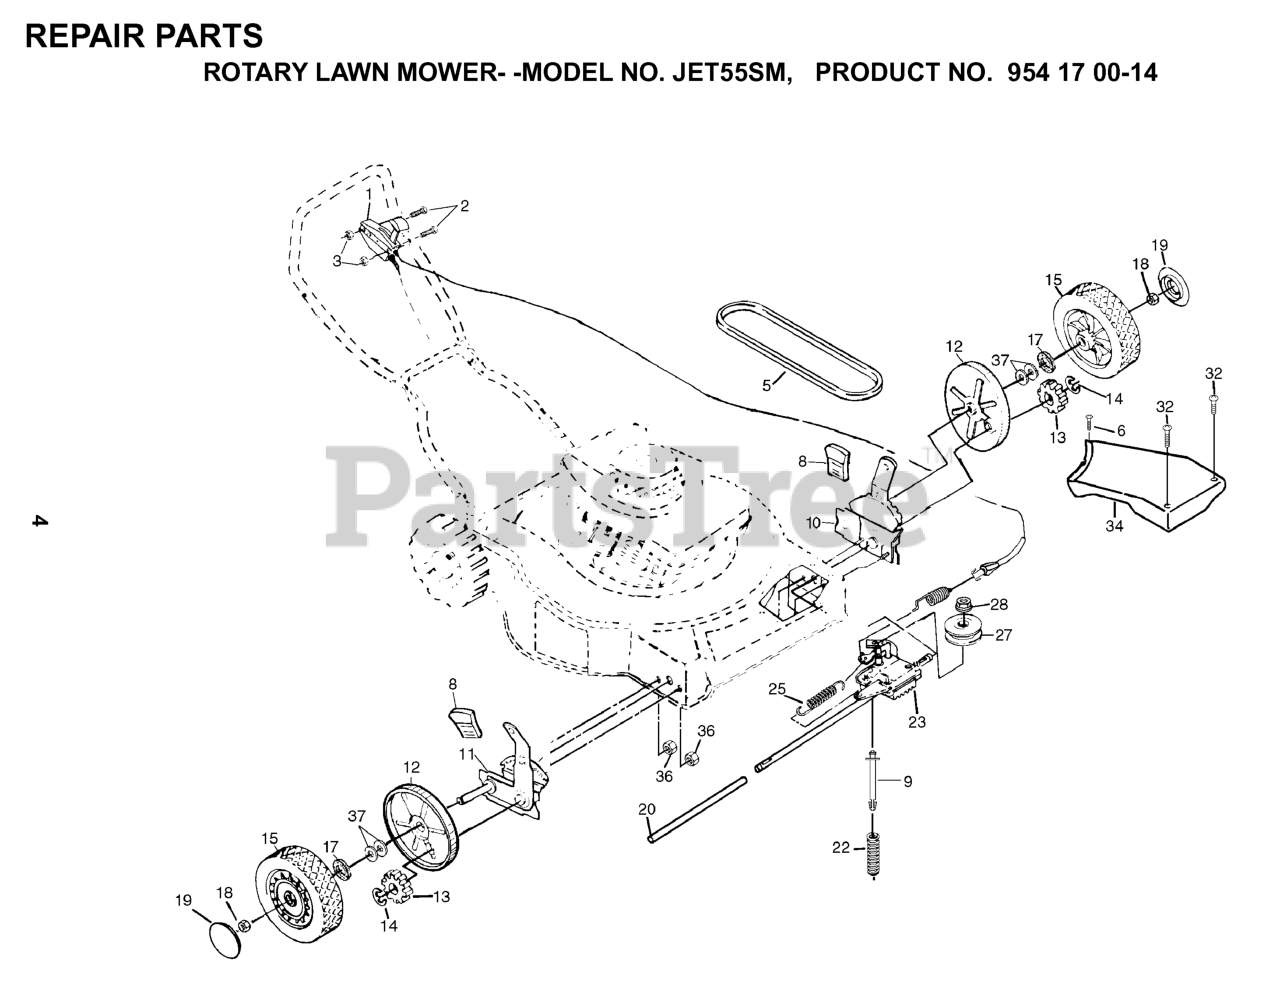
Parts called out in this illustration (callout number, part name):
1	DRIVE CONTROL
2	SCREW 1/4-20 X 2.12
3	NUT
5	BELT THERM .32
6	TAPPING SCREW
8	SELECTOR KNOB
9	SPRING RETAINER
10	WHEEL ADJUSTER ASSY (LEFT)
11	WHEEL ADJUSTER KIT RH
12	DUST SHROUD PM
13	PINION GEAR
14	E-RING 7/16 RE
15	WHEEL & TIRE 8 X 2
17	WASHER FLUT
18	HEX FLANGE LOCKNT
19	HUBCAP.8".GREY
20	DRV SHAFT TUBE PM
22	SPRING.EXTENSION
23	GEAR CASE ASMBLY
27	PULLEY
28	FLANGED LOCKNUT 3/8-16 ZINC
34	COVER DRIVE
36	NUT
37	WAVE WASHER
